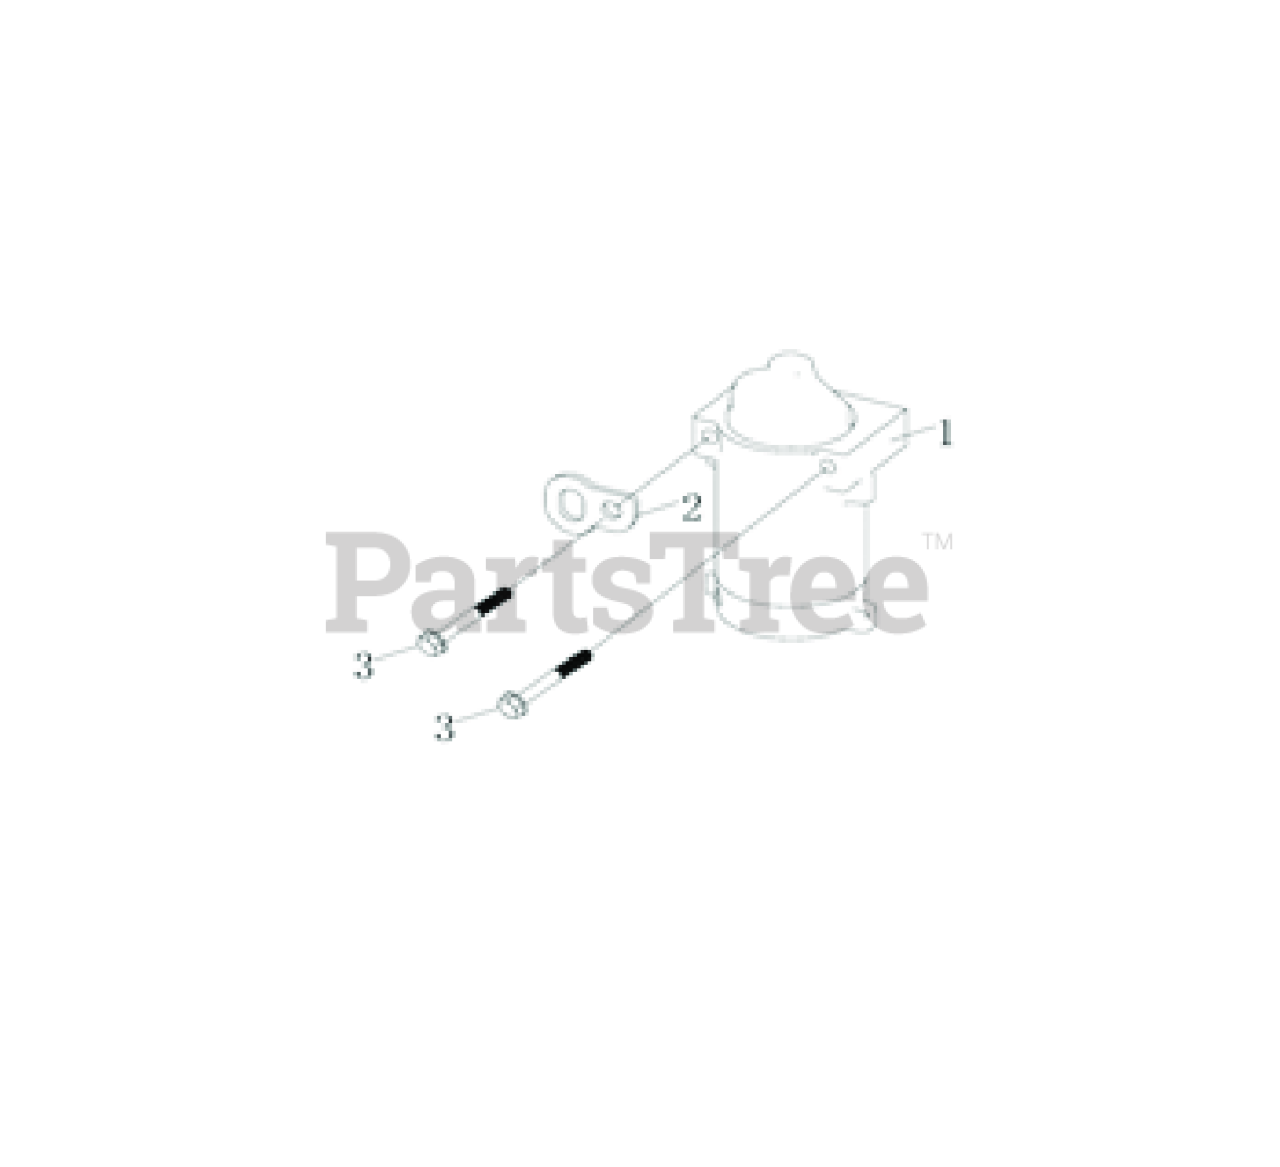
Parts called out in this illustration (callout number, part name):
1	Starter Motor
2	Bushing, .502" I.D.
3	Bolt, Flange
